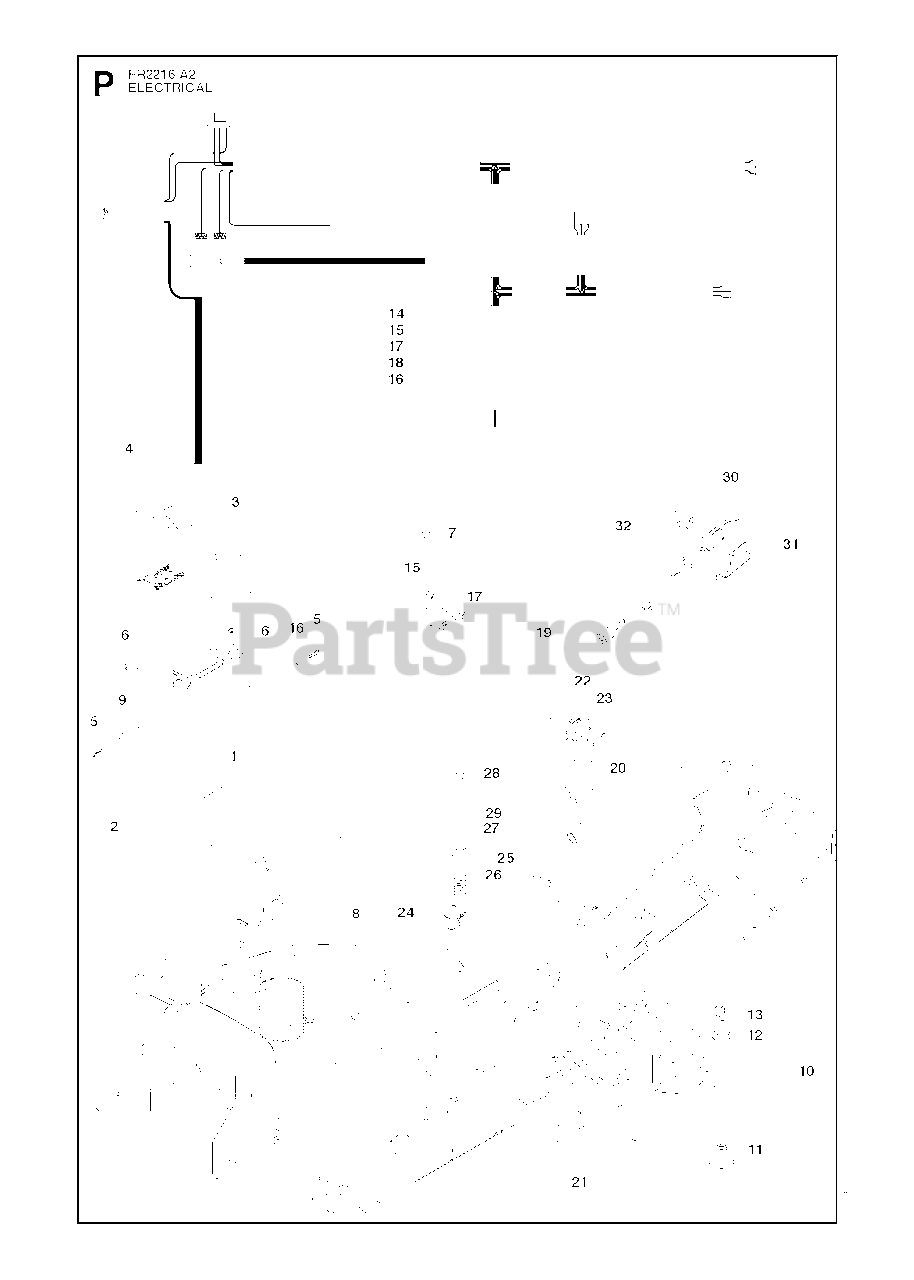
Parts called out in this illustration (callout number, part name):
5	SCREW EHHM
10	IGNITION SWITCH
11	IGNITION SWITCH
13	IGNITION KEY
27	SPACER TUBE
28	SCREW
29	WASHER BRB 8.4X17
30	MICRO SWITCH
